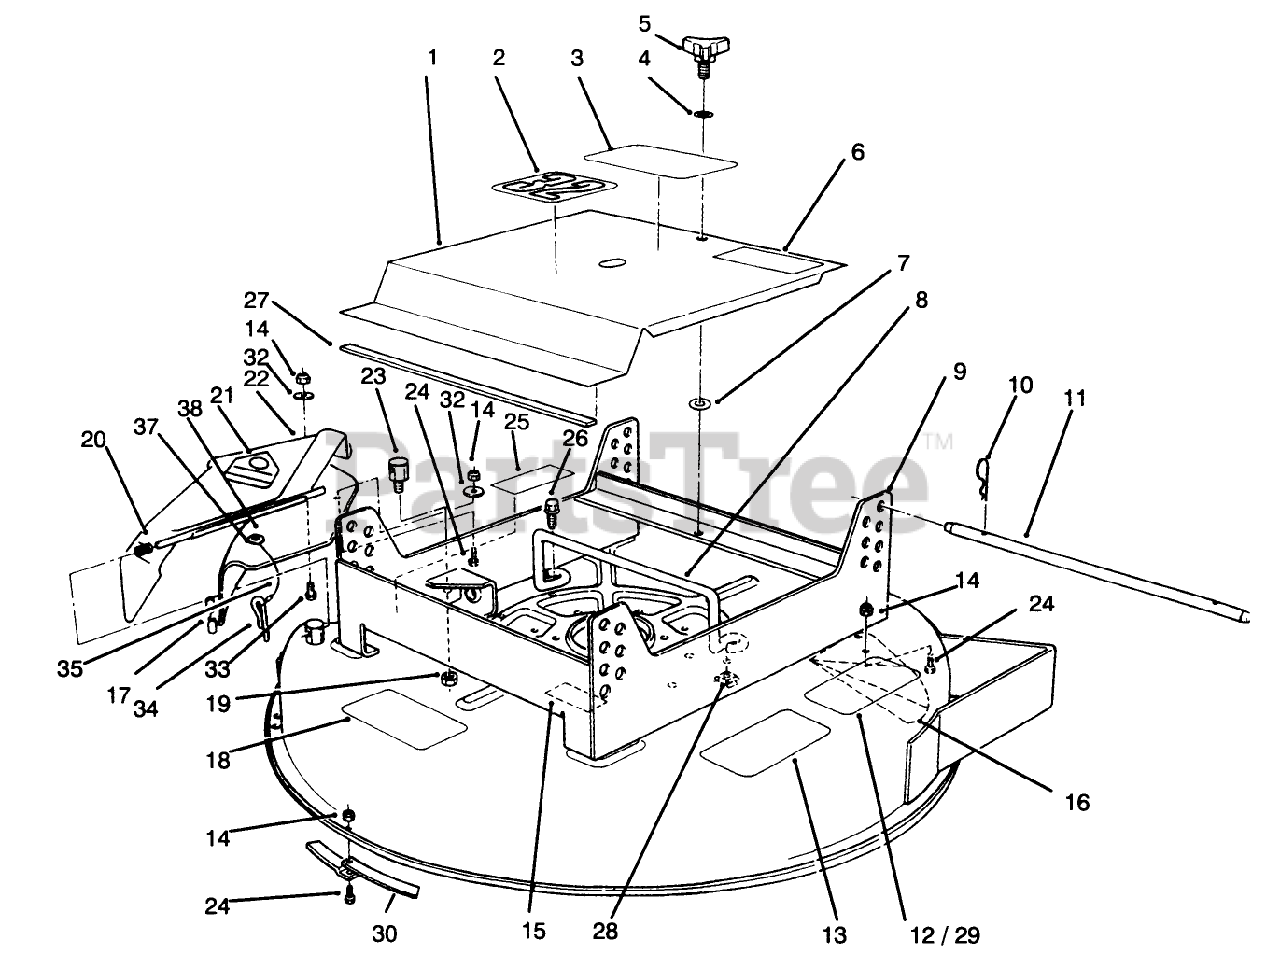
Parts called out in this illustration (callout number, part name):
1	Cover (Incl. Ref. #2-7 & 27)
2	DECAL
3	DECAL-PROLINE
4	WASHER-FLAT
6	DECAL-HOT
7	RING-RETAINING
8	GUIDE-BELT
9	32 INCH DECK ASM
10	PIN-HAIR
11	ROD-SUPPORT
12	DECAL
13	Decal
14	NUT-LOCK, NI
15	DECAL-DANGER
16	Kicker
17	MULCHER COVER ASM
18	DECAL-DANGER, THROWN OBJECT
19	NUT-LOCK, SIDE
20	SPRING
21	DECAL-DANGER
22	Deflector Asm. (Incl. Ref. #21)
23	POST-PIVOT
24	SCREW-HH
25	DECAL-DANGER
26	SCREW-HHF
27	STRIP-MAGNETIC
28	NUT-RETAINER
29	Decal-Height of Cut 2-5"
30	Ring-Deck
32	WASHER-PLAIN
33	SCREW-HH
34	PIN-LOCKING, CHUTE
35	LANYARD
37	WASHER-PLAIN
38	RIVET-BLIND
